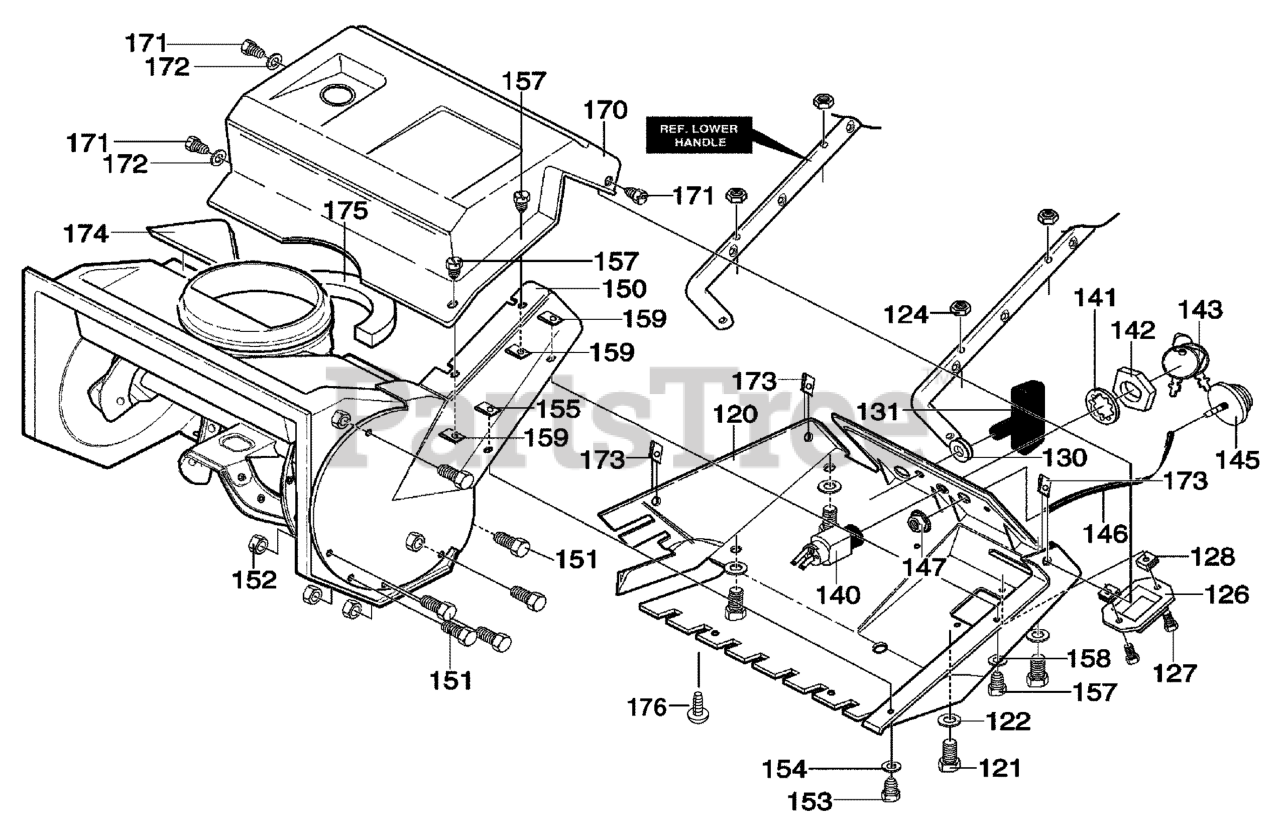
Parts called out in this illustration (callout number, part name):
120	COVER, BOTTOM
121	SCREW, 1/4-20X1.25
122	WASHER, FLAT .281X.63X.065
124	NUT, 1/4-20 YZ
126	COVER, CARB
127	SCREW, 1/4-14X.75
128	NUT, 1/4-10 SPEED J TYPE
130	GROMMET & WASHER, ROPE GUIDE
131	KNOB, STAND TEE
140	SWITCH, IGNITION
141	WASHER
142	NUT, 5/8-32 ACC
143	2 KEYS & RING
145	PRIMER, ENGINE
146	HOSE, PRIMER
147	KEPS NUT, 1/4-20
150	COVER, BELT
151	SCREW, 10-24X.50
152	NUT, #10-24
153	SCREW, 1/4-20X.50
154	WASHER, FLAT .281X.63X.065
155	NUT, 1/4-20 TINN
157	SCREW, 1/4-14X.75
158	WASHER, FLAT .281X.63X.065
159	NUT, 1/4-20 SPEED J TYPE
170	COVER, TOP
171	SCREW, 1/4-14X.75
172	WASHER, FLAT .281X.63X.065
173	NUT, 1/4-10 SPEED J TYPE
174	SEAL, FOAM
175	SEAL, STRIP CHUTE & GAS SEAL
176	SCREW 10-14 x 0.63
